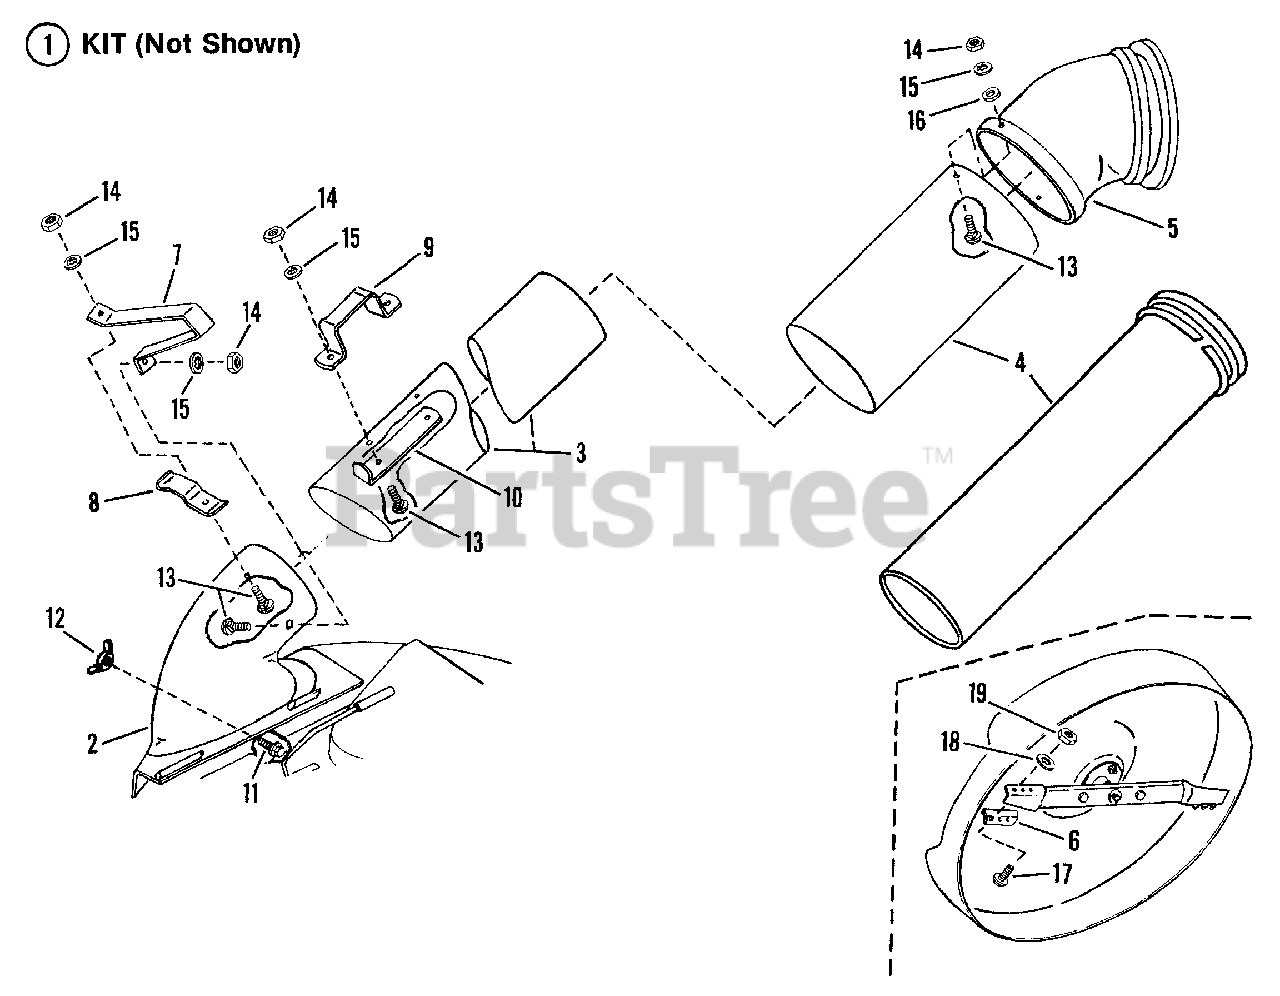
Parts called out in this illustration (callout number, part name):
1	KIT, Snapper Bag-N-Wagon (Complete)
2	ADAPTER, Deck
3	TUBE, Grass (8" Dia.)
4	TUBE, Grass (10" Dia.)
5	ELBOW, Grass Tube
6	AIR-LIFT, Blade
7	BRACKET, Stand-Off
8	LATCH, Tube
9	HANDLE, Tube
10	BASE, Tube Handle
11	BOLT, 5/16-18x1" Carriage
12	NUT, 5/16-18 Wing
13	BOLT, 1/4-20x3/4" Carriage
14	NUT, 1/4-20 Hex
15	WASHER, 1/4 Internal Tooth Lock
16	WASHER 5/16 Flat
17	SCREW, 5/16-24x21/32" Machine
18	WASHER, 5/16 Internal Tooth Lock
19	NUT, 5/16-24 Hex
